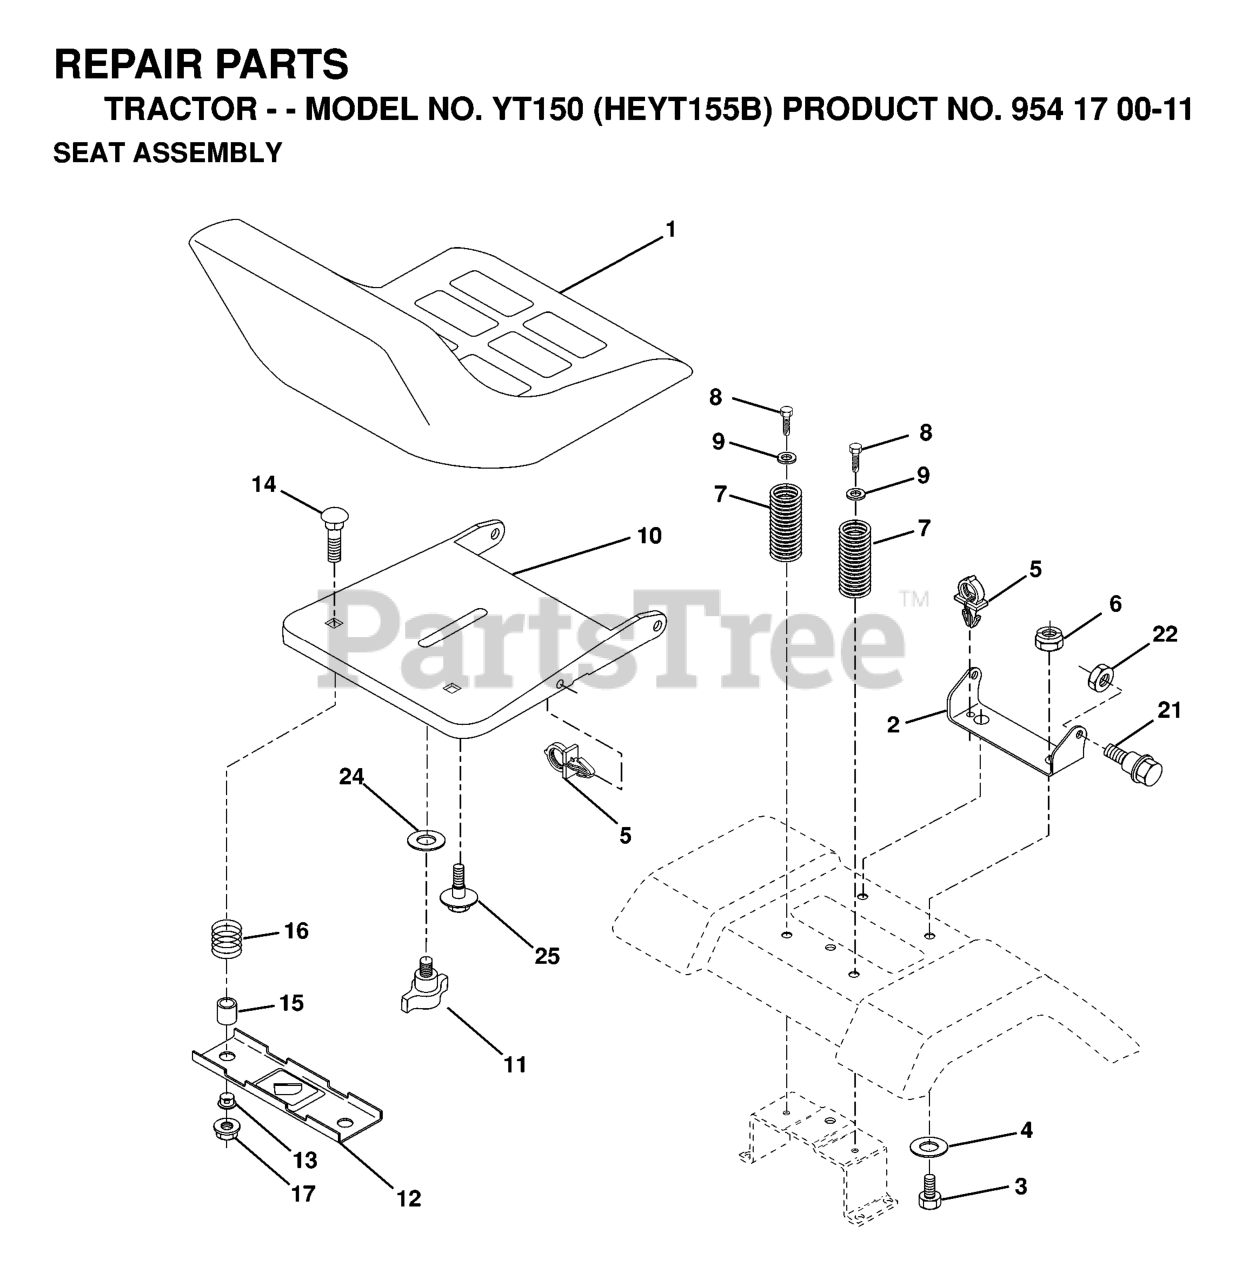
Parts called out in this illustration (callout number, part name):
1	SEAT, GRAY
2	SEAT PIVOT BRKT
3	BOLT
6	NUT
7	SPRING COMPRESSION
8	SCREW GTV
9	WASHER
10	PAN, SEAT
11	KNOB 1/2" YT
12	BRKT SWITCH
14	BOLT.ROUND.HEAD.SQUARE.NECK
15	SPACER SPLIT 28X.96
17	NUT T
21	BOLT SHOULDER 5/16-18
22	NUT.71038.31-18.HEX.NYLOCK
25	BOLT,SHOULD
